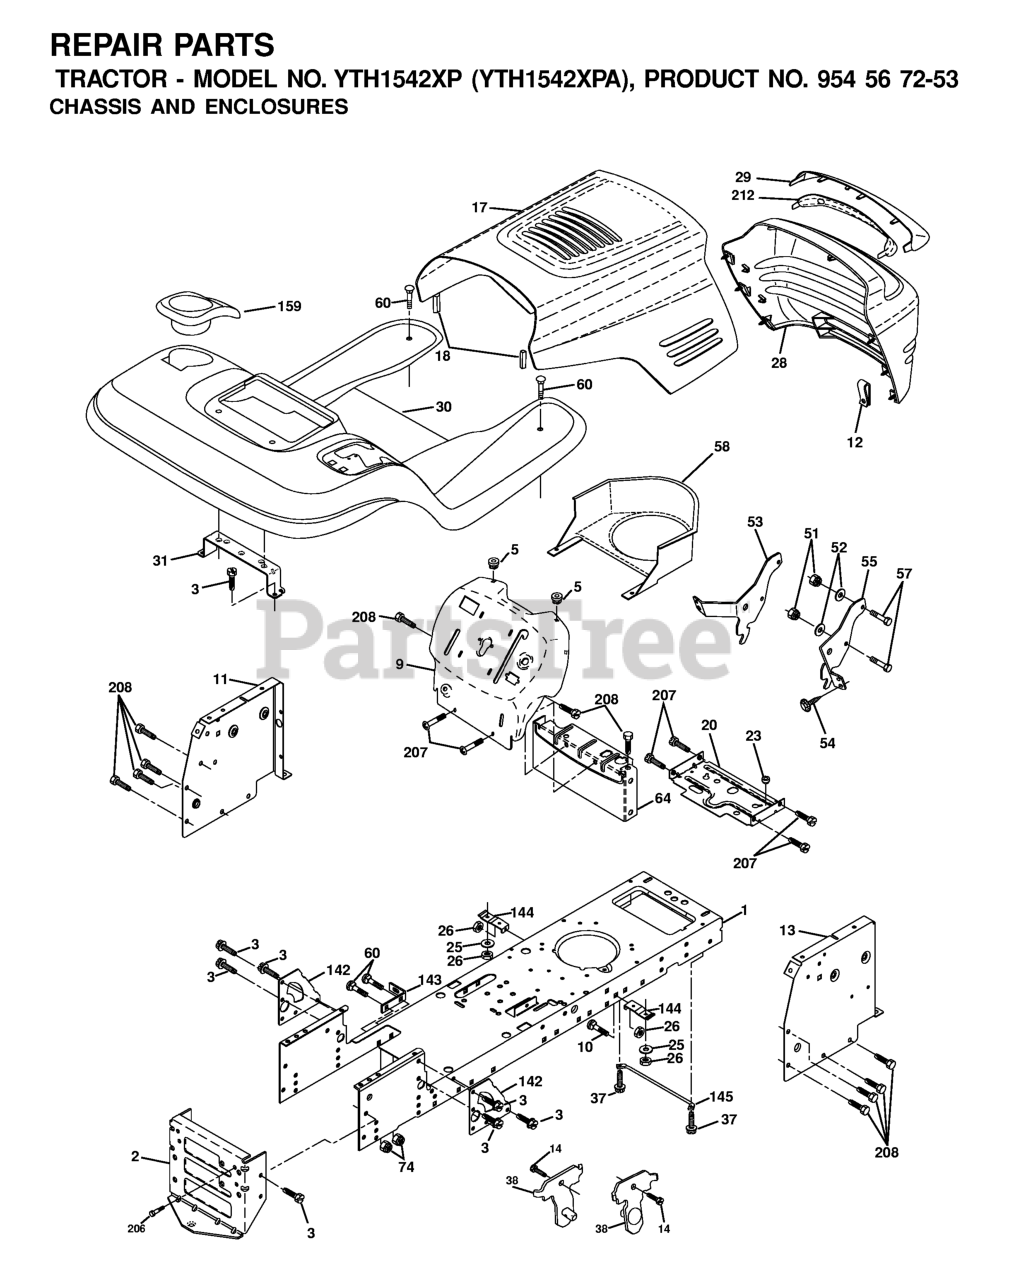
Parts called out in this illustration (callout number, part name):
1	CHASSIS STAMPING
2	DRAWBAR, 12GA
3	SCREW 3/8-16X3/4
5	BUMPER.RUBBER.HOOD
10	BOLT D
11	PANEL DASH LH
13	PANEL ASM, DASH RH
17	HOOD ASM.
18	BUMPER HOOD T
20	PLATE MTG
23	BUSHING.SNAP.NYL.BLK.
25	WASHER
26	NUT
28	GRILLE ASM
29	LENS
31	BRACKET.SUPPORT.FENDER
37	Screw 5/16-18 x 1/2 Hex, Self Tapping 5/16-18 x 1/2
38	BRACKET
44	STRAP
51	LOCKNUT.NYLOC.1/4-20
53	BRACKET.GRILLE.LH
54	SCREW.HEX.WS.HD.8-18 X 7/8
57	BOLT
58	AIR CONDUCTOR
60	Bolt - Rd. Hd. Sq. Neckiage 3/8 16 x 3/4
64	DASH LOWER
142	PLATE
143	BRACKET, SWAY BAR
144	BRACKET FOOTREST
145	ROD PIVOT CHASSIS/HOOD
159	CUPHOLDER
196	SCREW CRT
206	SHOULDER BOLT 5/16-18TT
207	SCREW, 5/16-18 X 1/2
208	SCREW 3/8-16X1/2
212	REPL BY 532 1745-03
